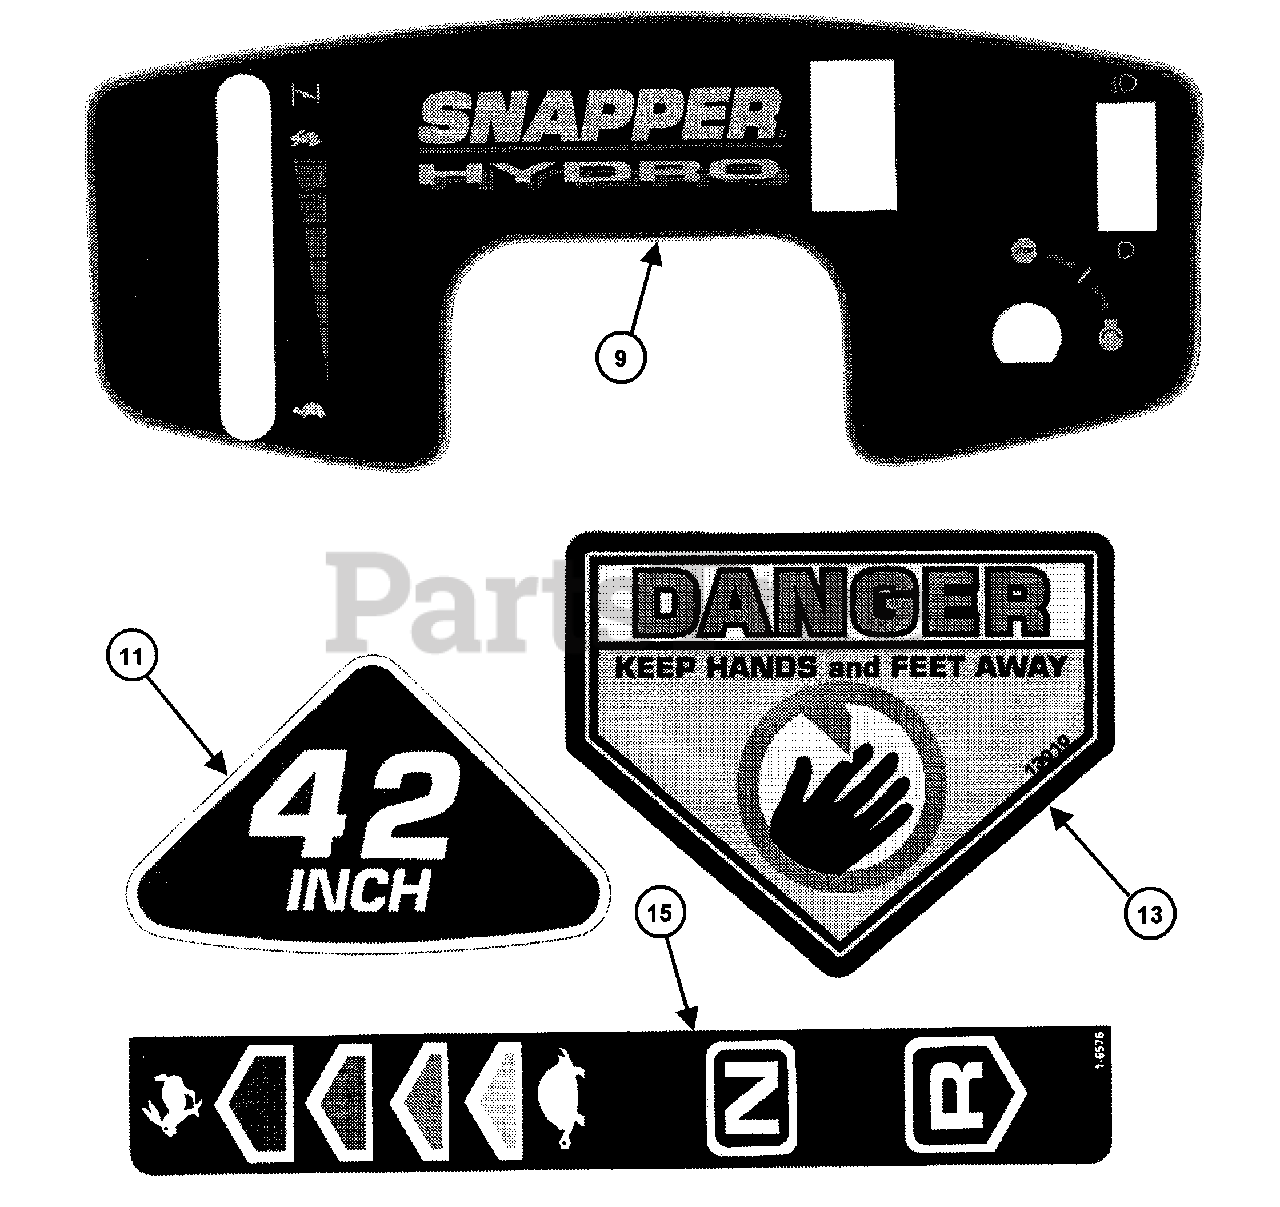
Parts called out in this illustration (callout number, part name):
9	DECAL, Console w/Headlights
11	DECAL, 42" Deck
13	DECAL, Danger CPSC
15	DECAL, Shift Cover
